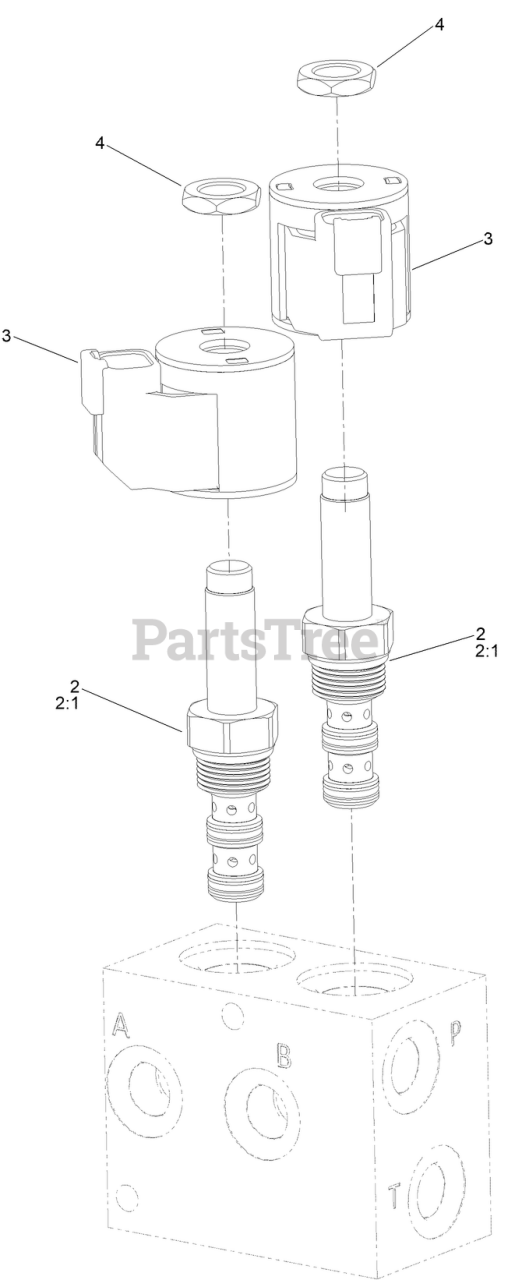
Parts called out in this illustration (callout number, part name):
2	VALVE-3 WAY
2:1	SEAL KIT
4	NUT-COIL
